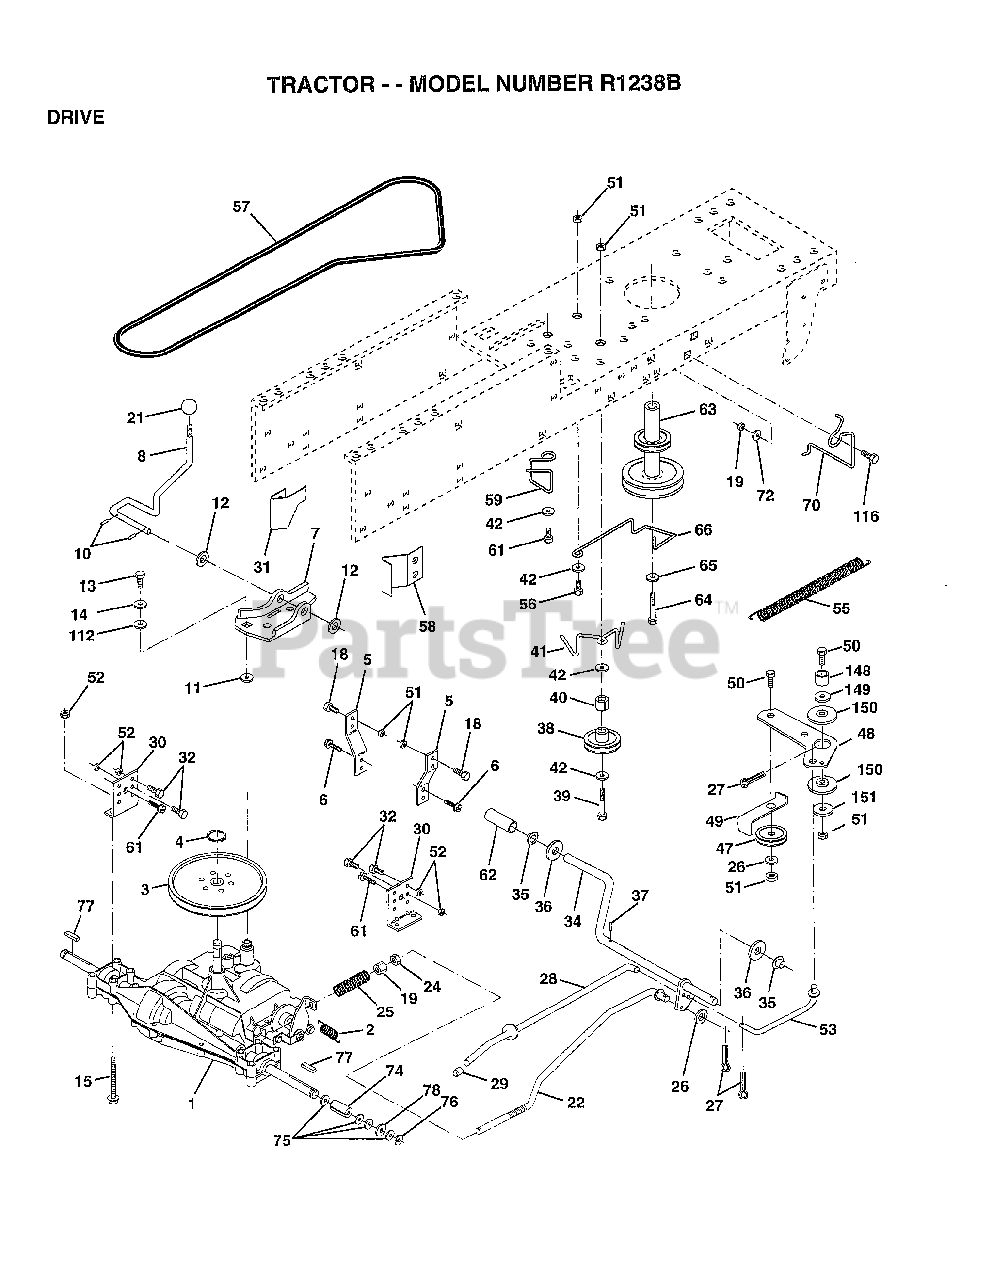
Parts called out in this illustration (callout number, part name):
1	TRANXAXLE ASM
2	SPRING.BRAKE.RETU
3	PULLEY TRANS
5	STRAP TORQUE
6	SCREW
7	BRKT.SADDLE.SHIFT
8	SHIFT ROD
10	PIN COTTER 1/8
11	WASH-SHFT PLT LT
12	WASHER
13	BOLT.1/4-28.W/PAT
14	LOCKWASHER
15	BOLT.HX.FLG.5/16
18	BOLT
19	NUT
21	KNOB T (1/2-HOLE)
22	BRAKE ROD
24	NUT
25	SPRING ROD LT
26	WASHER
27	COTTER PIN
28	ROD.BRAKE.PARK.LT
29	PLUNGER CAP T
30	TRANSAXLE MTG BKT
31	"KEEPER,BELT LH T"
32	BOLT
34	SHAFT ASM-PEDAL F
35	NYLON BEARING
36	WASHER LT
38	PULLEY.IDLER.FLAT
39	BOLT
40	SPACER T
42	WASHER
48	BELLCRANK.CLUTCH
49	RETAIN BELT
53	"LINK, CLUTCH T"
55	"SPRING, RETURN LT"
57	"V-BELT,95.3"
58	"KEEPER,BELT RH T"
59	KEEPER BELT CNTSP
61	SCREW
62	PEDAL COVER T
63	PULLEY.ENGINE
64	BOLT
65	LOCKWASHER
66	KEEPER-BELT
70	KEEPER BELT ENG
72	WASHER
74	SPACER LT
76	E-RING LT
77	SQUARE KEY
78	WASHER
112	WASHER LT
116	BOLT RDHD 3/8-16
149	SPACER RETAINER
150	BUSHING.NYLON
151	WASHER
